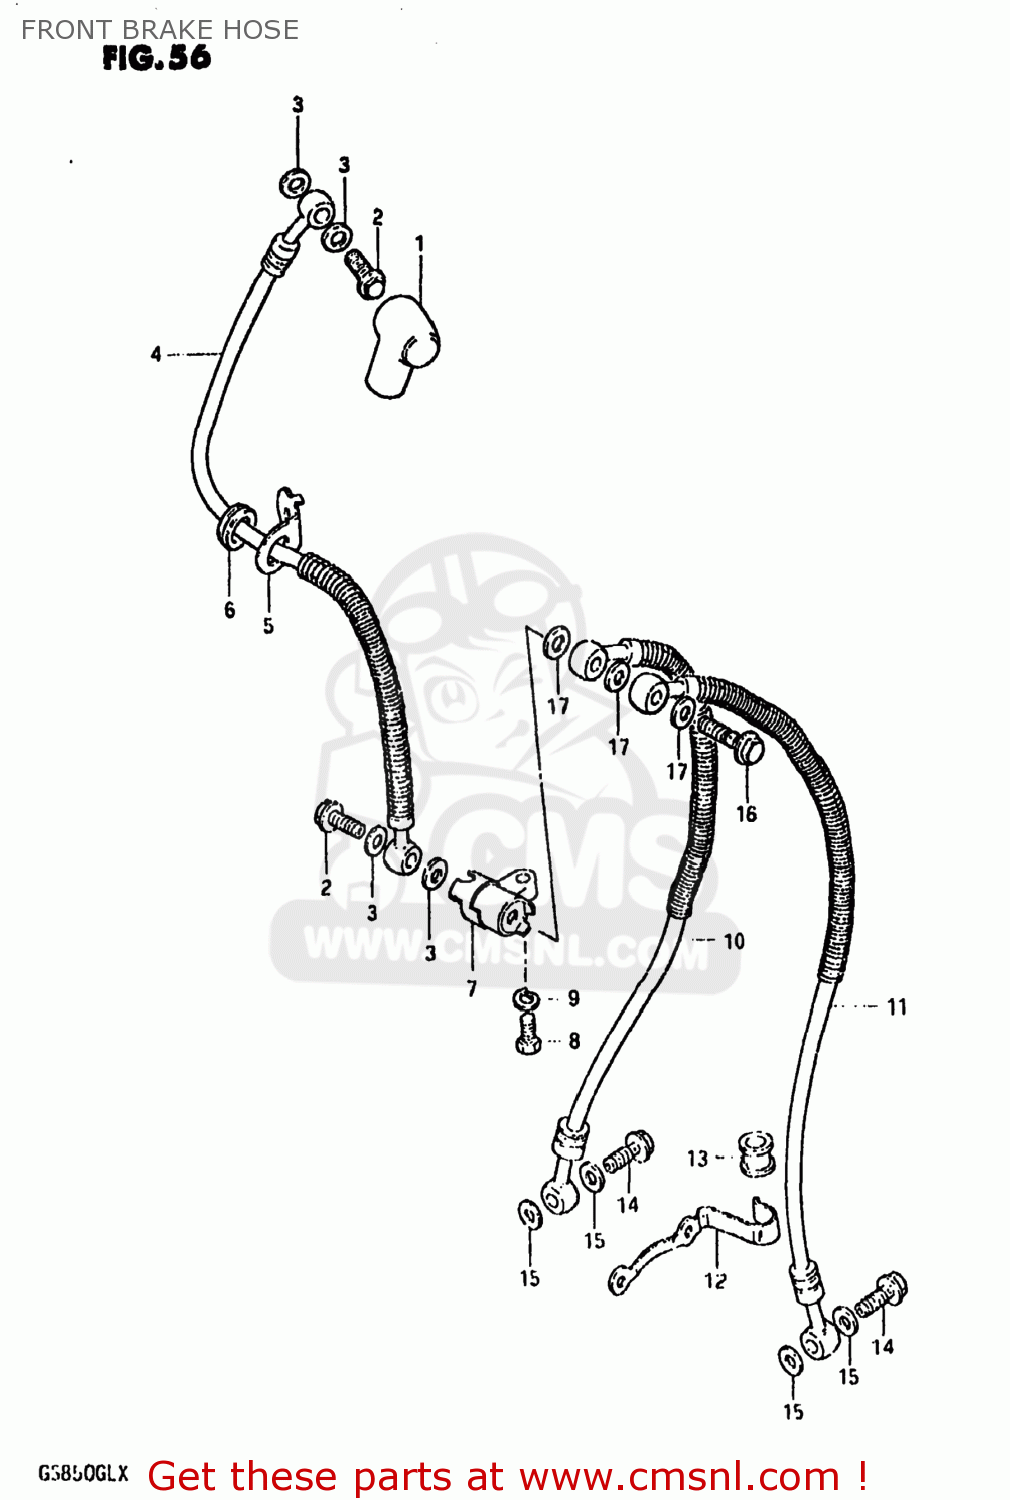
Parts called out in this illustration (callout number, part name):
1	BOOT,MASTER CYLINDER
2	BOLT,UNION
3	WASHER
4	HOSE,FRONT BRAKE NO.1
5	GUIDE,BRAKE HOSE
6	GROMMET
7	JOINT,BRAKE HOSE
8	BOLT
9	LOCK WASHER
10	HOSE,FR BRAKE NO.2,L
11	HOSE,FR BRAKE NO.2,L
12	GUIDE,BRAKE HOSE NO.2
13	BUSH,BRAKE HOSE GUIDE,NO.2
14	BOLT,UNION
15	WASHER
16	BOLT,UNION
17	WASHER
